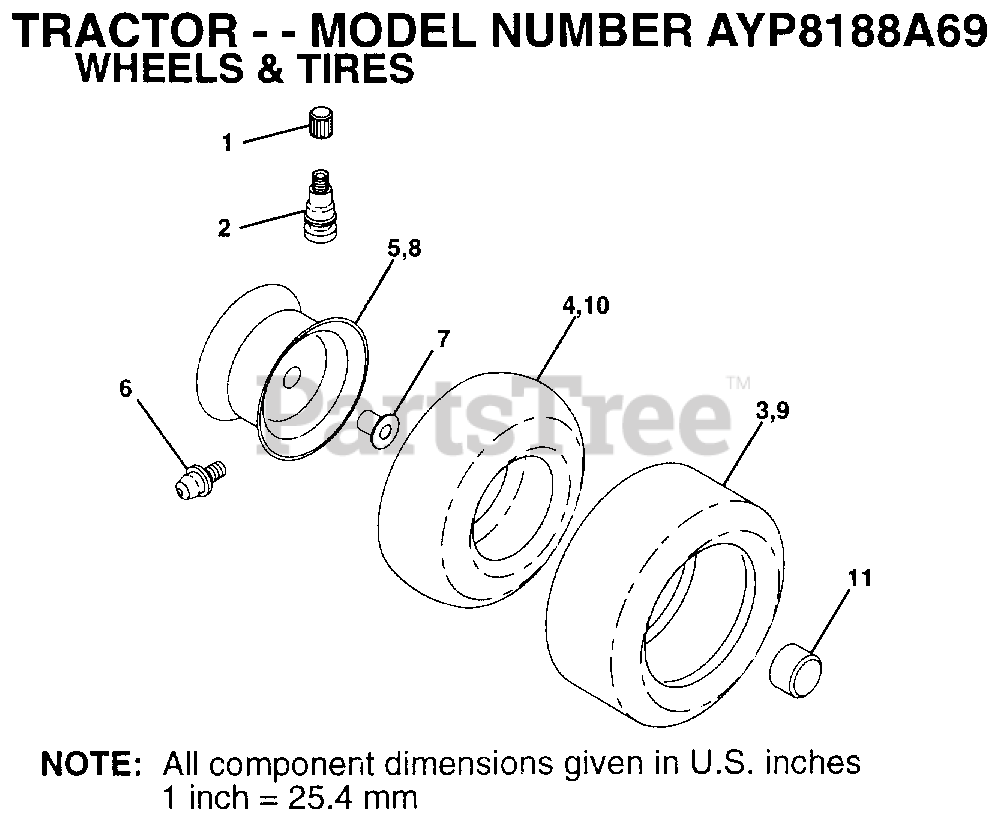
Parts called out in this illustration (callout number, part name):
1	VALVE CAP
2	VALVE STEM LT
4	TUBE.16X6.5/7.5-8
5	"RIM ASM 8"" FRT"
6	ZERK FITTING M
7	"FLANGE, BEARING"
8	"RIM ASM 12"" REAR"
10	TUBE.23X8/10-12
11	HUB CAP
